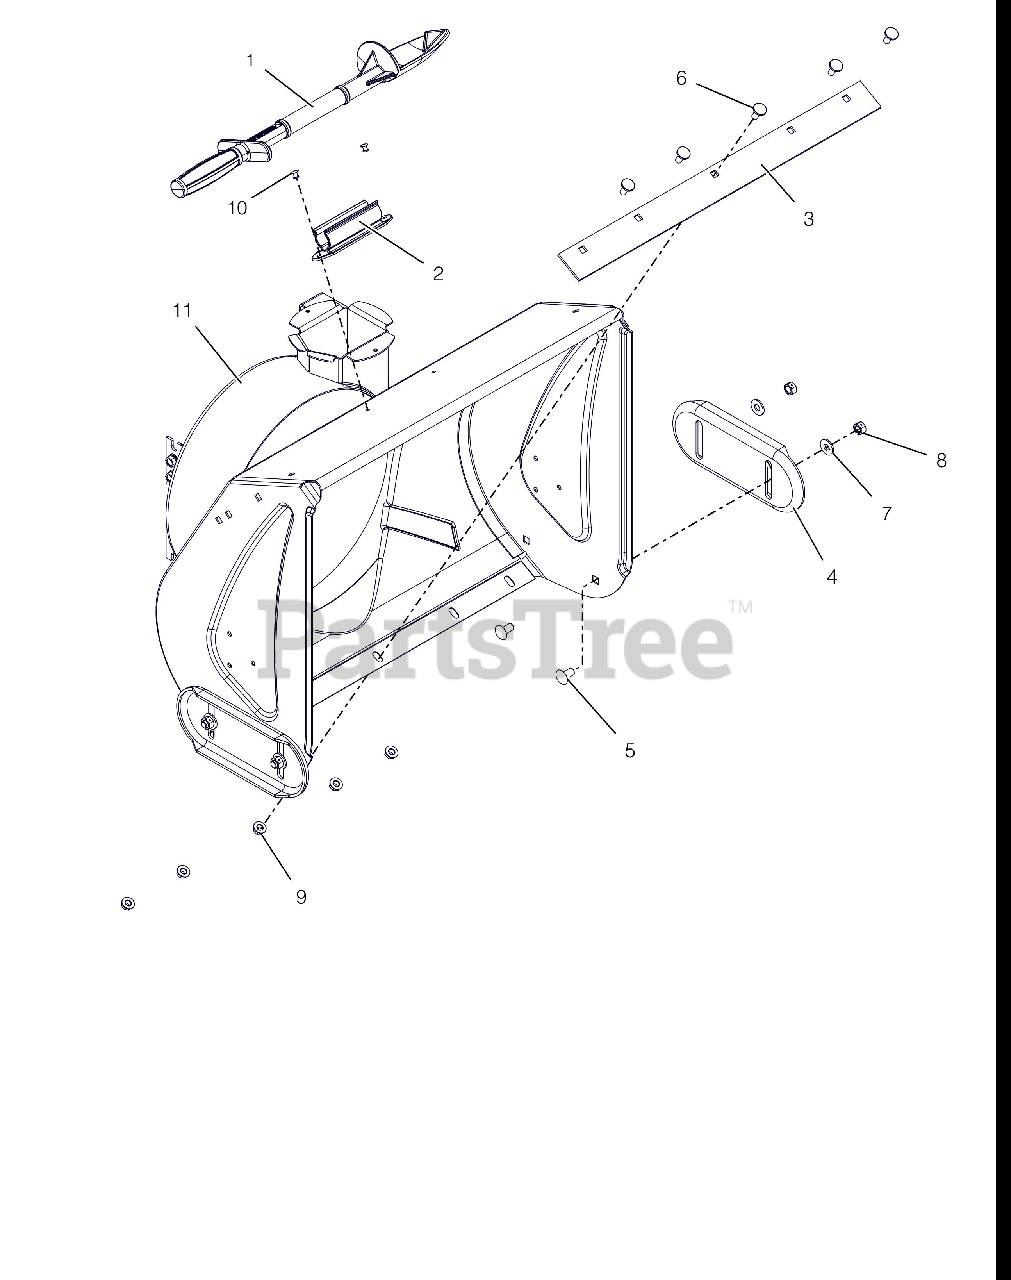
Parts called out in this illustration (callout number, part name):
1	DEVICE, SNOW CLEAN OUT
2	MOUNT, SNOW CLEAN OUT
3	SCRAPER BLADE, 22" COMPACT HI
4	SKID SHOE, REVERSIBLE
5	@BLT-RHDSSQNK .38-16X.75 G5YZ
6	BOLT, MODIFIED HEAD CARRIAGE
7	@WSHR-FL-STL.38X.875X.083 YWZC
8	@NUT-LK-CTR .38-16 YWZC
9	@NUT-LK-TOP-FLG .31-18 YWZC
10	RVT-POP .187 YZ
11	BLOWER HOUSING, 22"
